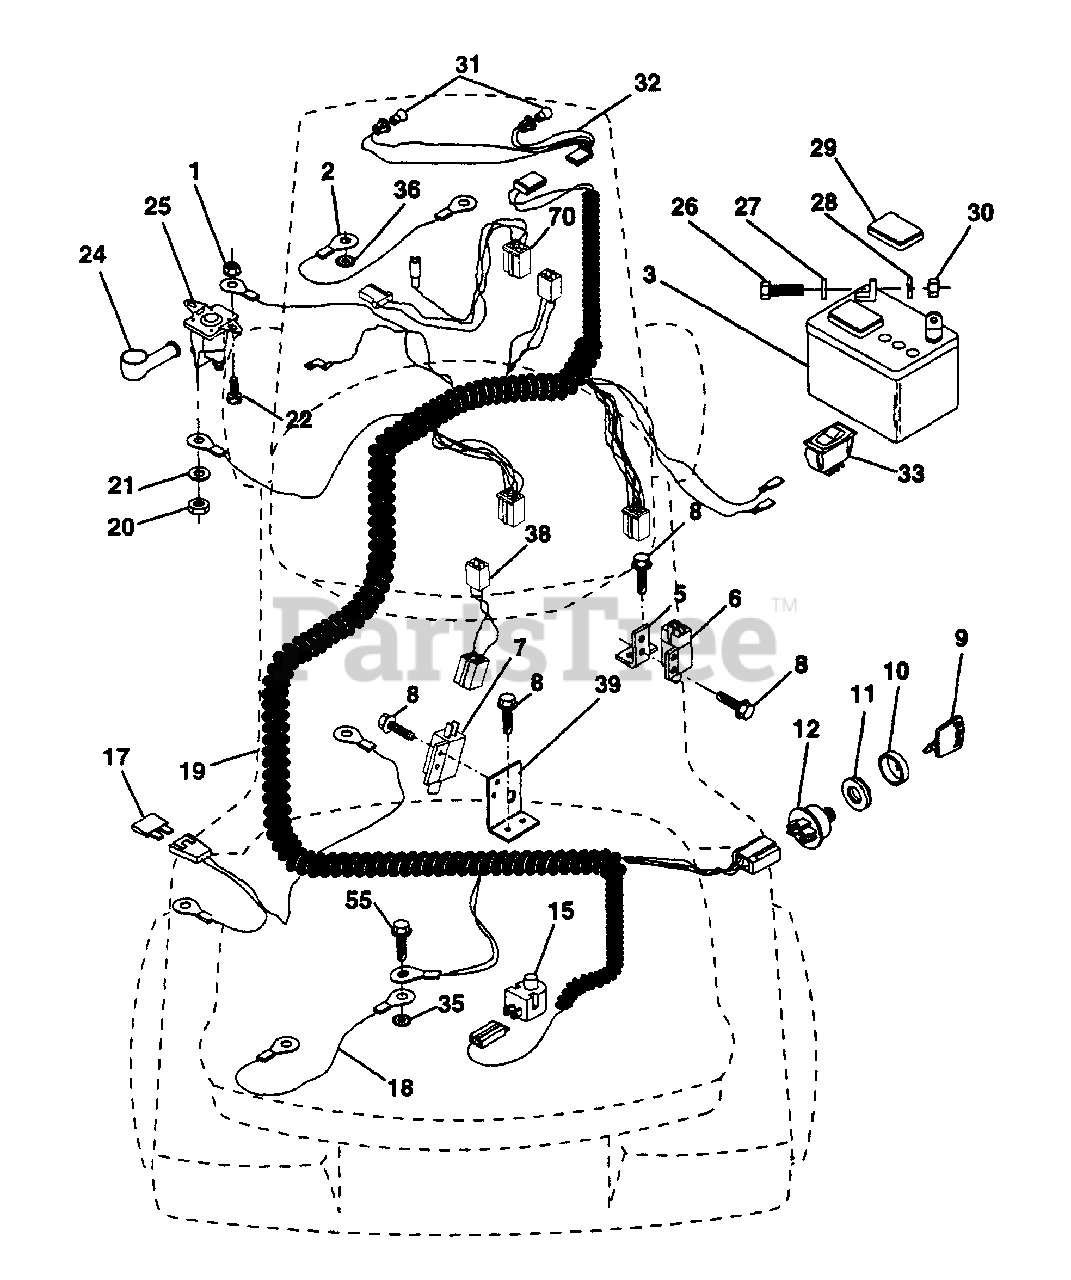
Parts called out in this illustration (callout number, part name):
1	Nut, Hex, Keps 1/4-20
2	Assembly, Cable
3	Battery
5	Bracket, Switch
6	Switch, Interlock, 2 Terminal
7	Switch, Interlock, 4 Terminal
8	Screw, Hex Head, Self-Tapping #10-24 x 1/2
9	Key, Molded
10	Cover, Ignition Key
11	Nut, Ignition
12	Switch, Ignition
15	Switch, Plunger
18	Assembly, Cable
19	Harness, Ignition
20	Nut, Hex, Jam 1/4-20
21	Washer, Lock 1/4
22	Bolt, Hex, Fin. 1/4-20 UNC x 1/2 Grade 5
24	Cover, Terminal
25	Solenoid
26	Bolt, Hex Head 1/4-20 UNC x 3/4
27	Washer 9/32 x 5/8 x 16 Gauge
28	Washer, Lock 1/4
29	Cap, Battery
30	Nut, Hex, Fin. 1/4-20 UNC
31	Bulb, Light
32	Harness, Headlight
33	Switch, Light
35	Washer, Lock, External Tooth 5/16
36	Washer, Lock, Internal Tooth 1/4
38	Harness Adapter
39	Bracket, Switch Clutch
55	Screw, Thdrol 5/16-28 x 1/2
70	Harness Engine
